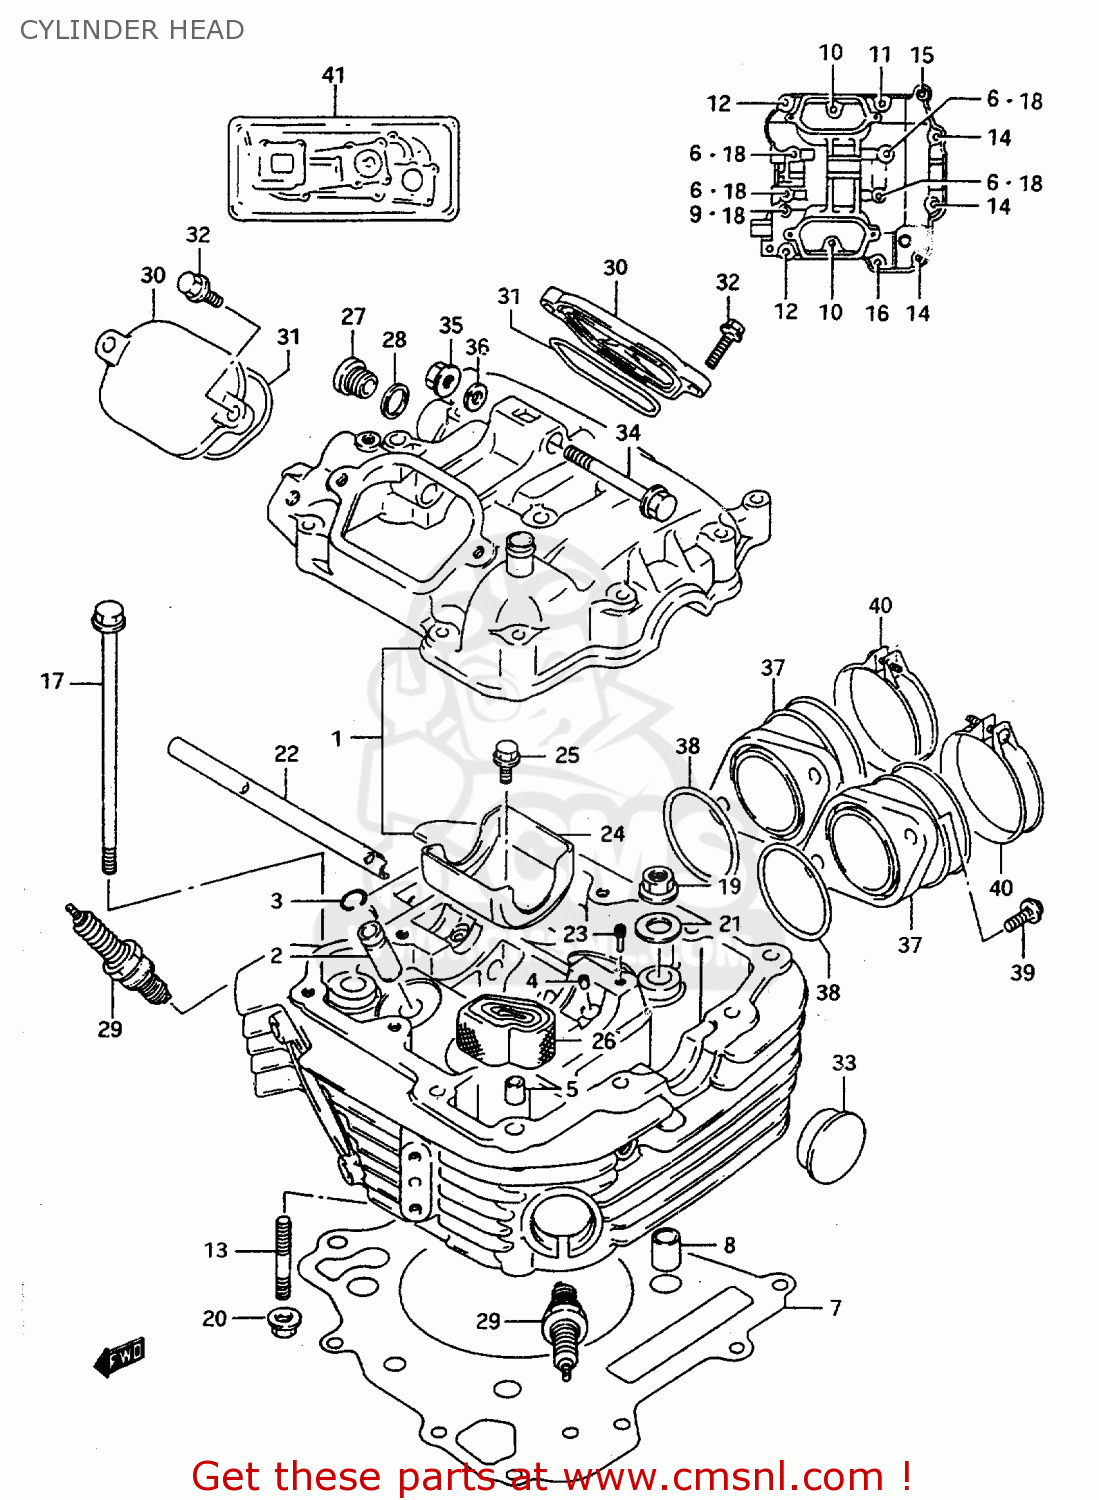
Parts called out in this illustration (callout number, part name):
1	HEAD ASSY, CYLINDER
2	GUIDE,VALVE
3	RING,SNAP
4	JET,OIL GALLERY
5	PIN(6.2X8X11)
6	BOLT(6X55)
7	GASKET,CYLINDER HEAD (NAS)
8	PIN
9	BOLT
10	BOLT
11	BOLT
12	BOLT
13	BOLT,STUD(8X31)
14	BOLT(6X125)
15	BOLT(6X115)
16	BOLT(6X105)
17	BOLT(8X155)
18	GASKET(5.8X13X1.2) (NAS)
19	NUT
20	NUT
21	WASHER (10.5X22X2.3)
22	PIPE,CYLINDER HEAD OIL
23	SCREW (L:19.5)
24	PLATE, OIL CHAMBER
25	BOLT
26	SEPERATOR,OIL
27	PLUG,14X12
28	GASKET(13.8X18.8X4.8) (NAS)
29	PLUG,SPARK(DPR9EA-9)
30	CAP,INSPECTION
31	O RING,INSPECTION CAP
32	BOLT
33	PLUG(OD:30)
34	BOLT(8X53)
35	NUT
36	LOCK WASHER
37	PIPECOMP,INT
38	O RING(D:2.4,ID:39.7)
39	SCREW
40	CLAMP
41	GASKET SET
